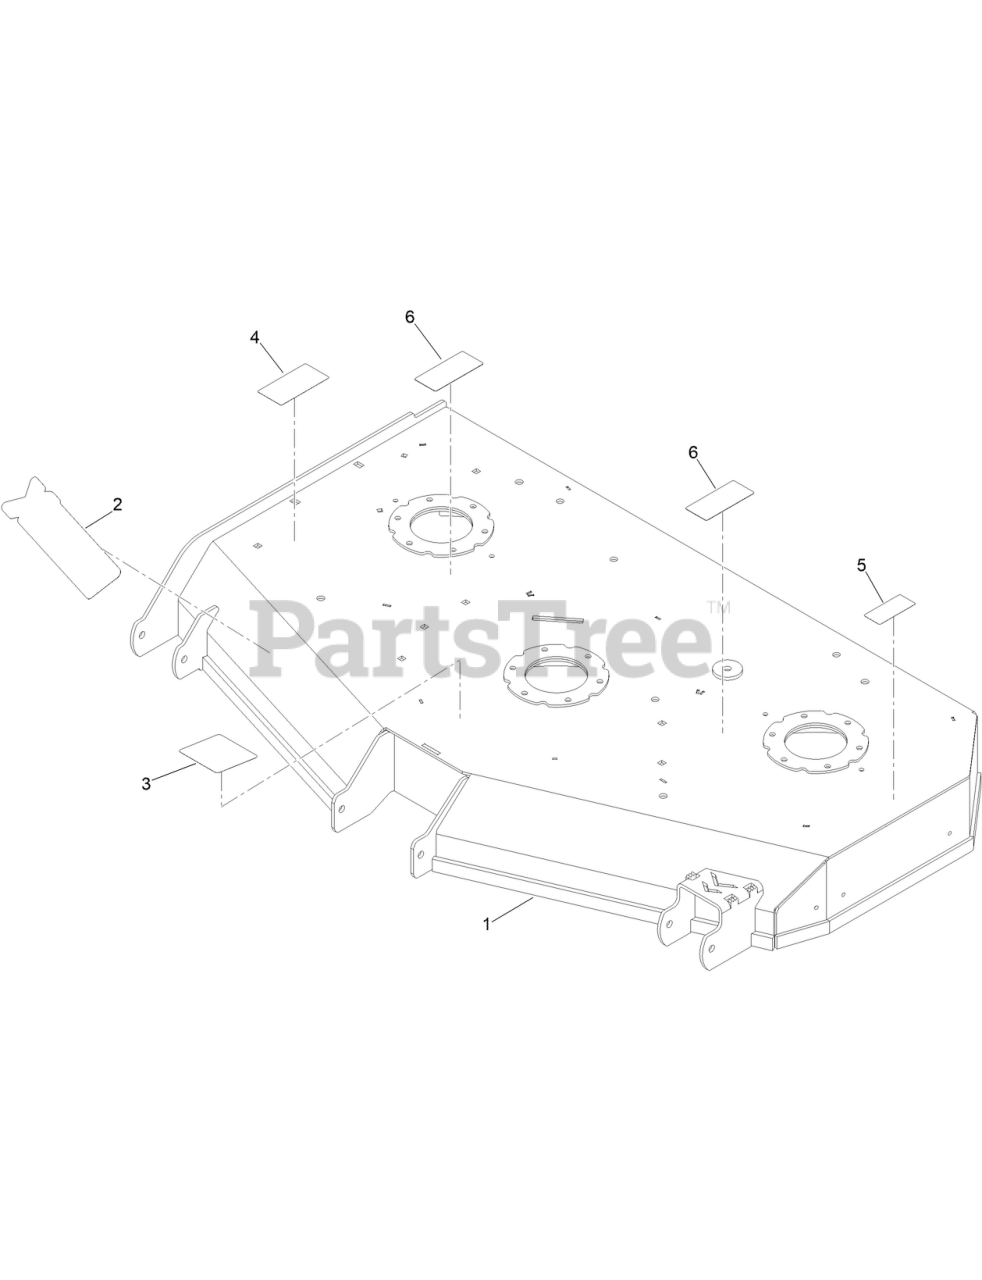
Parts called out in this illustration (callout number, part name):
1	DECK ASM-54 PAINTED
2	DECAL-XTF
3	DECAL-DECK BELT ROUTING
4	DECAL-DANGER, DECK
5	DECAL-SAFETY BLADE TORQUE
6	DECAL-ROTATING FAN HAZARD
